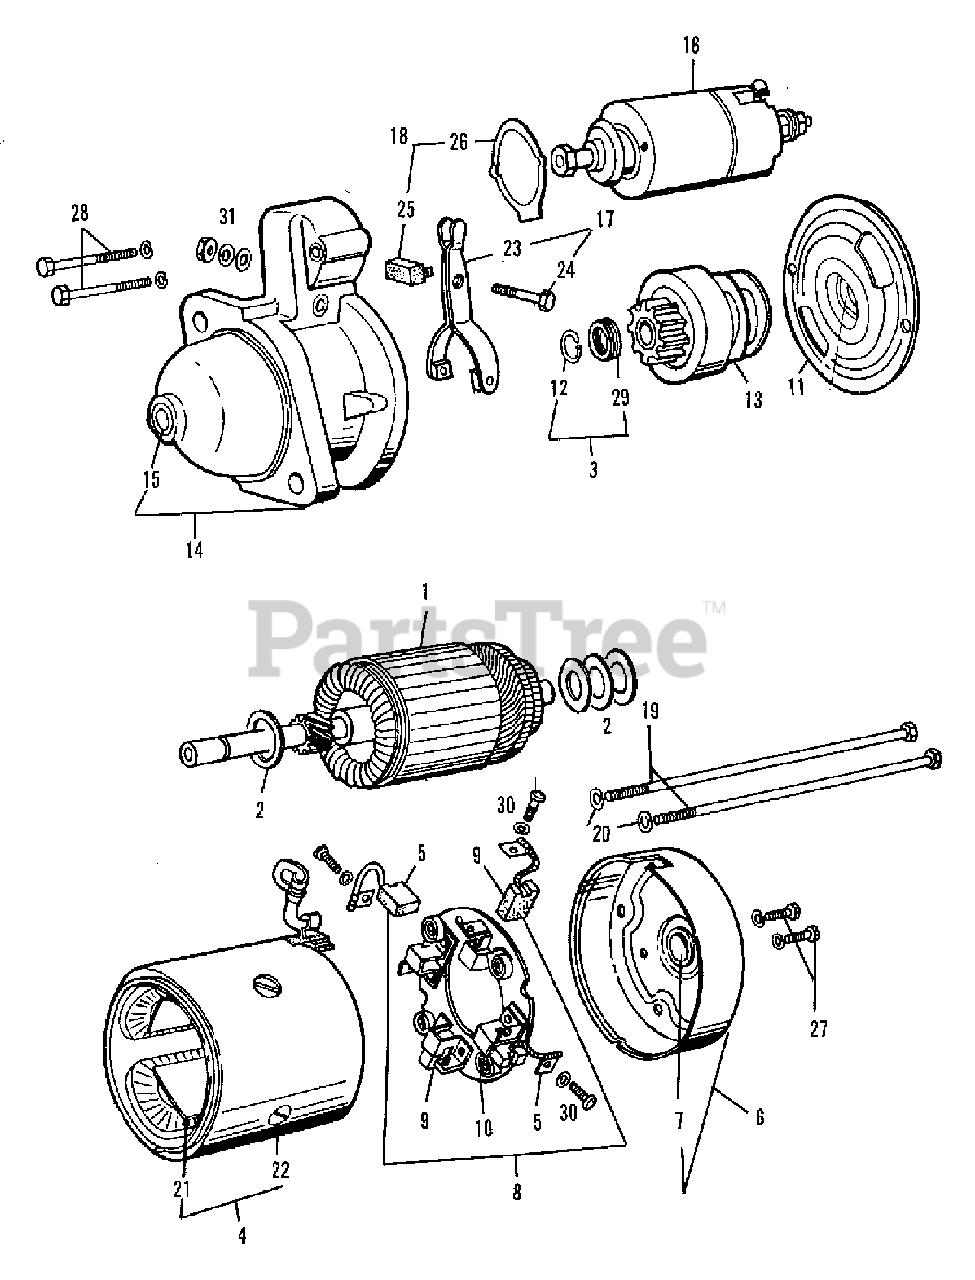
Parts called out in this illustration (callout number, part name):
1	ARMATURE ASSEMBLY
2	WASHER, kit thrust
4	YOKE ASSEMBLY (Incl. Items 21 & 22)
5	BRUSH (+)
6	COVER ASSEMBLY, rear (Incl. Item 7)
7	BEARING, rear cover
8	HOLDER ASSEMBLY, brush (Incl. Items 5, 9 & 10)
9	BRUSH (-)
10	SPRING, brush
11	BEARING ASSEMBLY, center (Incl. Item 12)
12	STOPPER PINION
13	PINION ASSEMBLY
14	CASE ASSEMBLY, gear (Incl. Item 15)
15	BEARING, gear case
16	SWITCH ASSEMBLY, magnetic
17	LEVER SET, shift (Incl. Items 23 & 24)
19	BOLT, through
21	COIL ASSEMBLY, field
22	SCREW, pole core set
23	LEVER, shift (Not Sericed; Order 2097857 LEVER SET)
24	PIN, shift lever
25	COVER, dust
26	COVER, dust
27	SCREW, M5 x 0.7 x 12
28	BOLT, M6 x 1.0 x 46)
29	CLIP, pinion stopper
